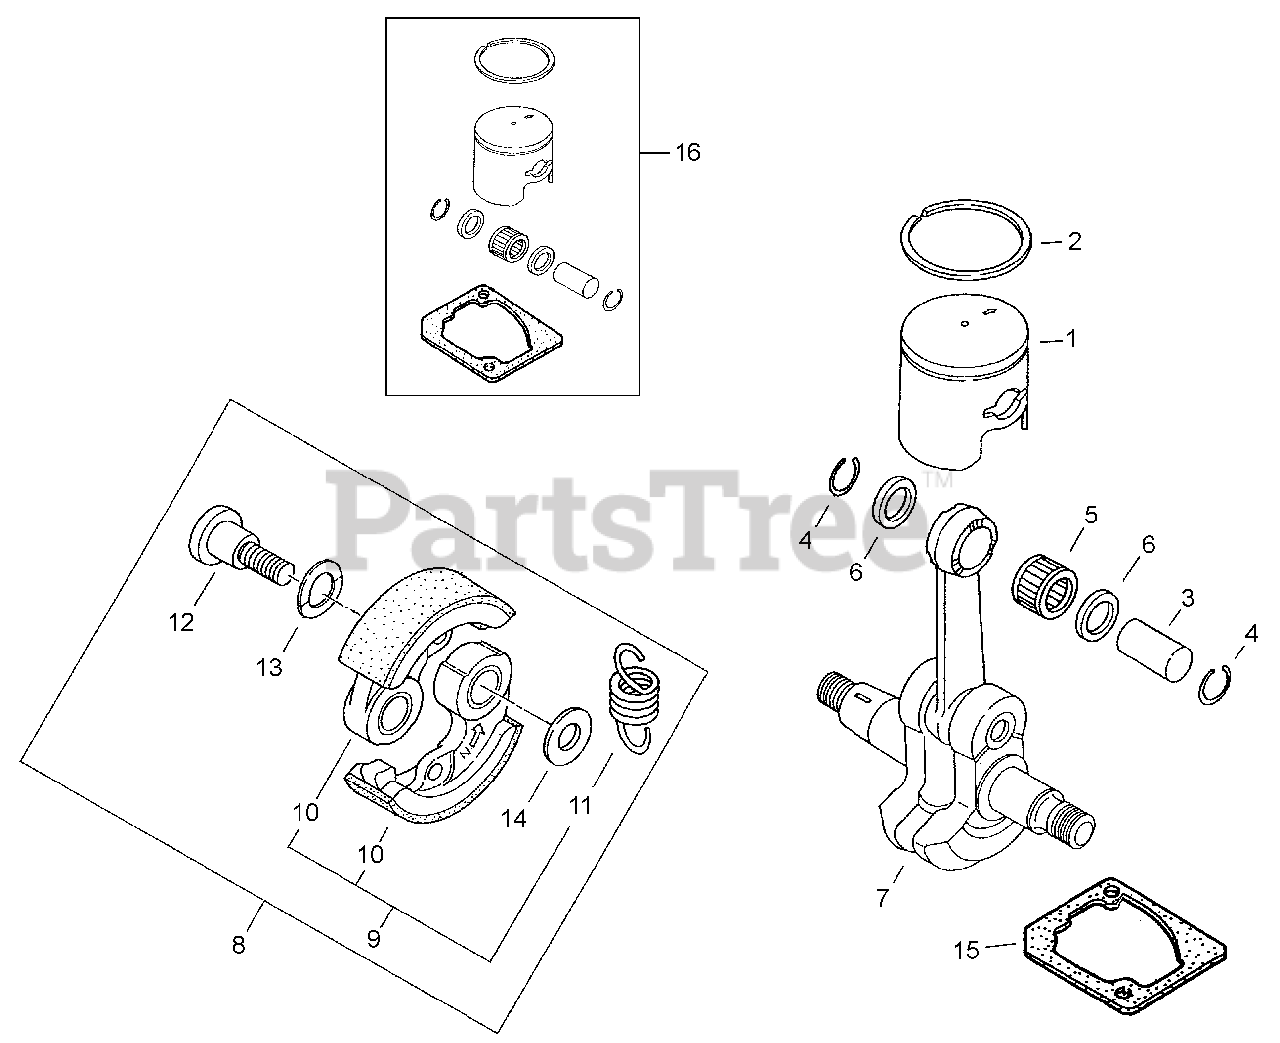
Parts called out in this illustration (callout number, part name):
2	RING, PISTON
3	PIN, PISTON
4	RING, SNAP
4-1	PISTON
5	BEARING, NEEDLE
6	WASHER, THRUST
7	CRANKSHAFT
8	SHOE ASSY, CLUTCH
9	CLUTCH KIT
10	SHOE, CLUTCH
11	SPRING, CLUTCH
12	BOLT
13	WASHER, SPRING
14	WASHER 6 MM
15	GASKET, CYLINDER
16	PISTON KIT
